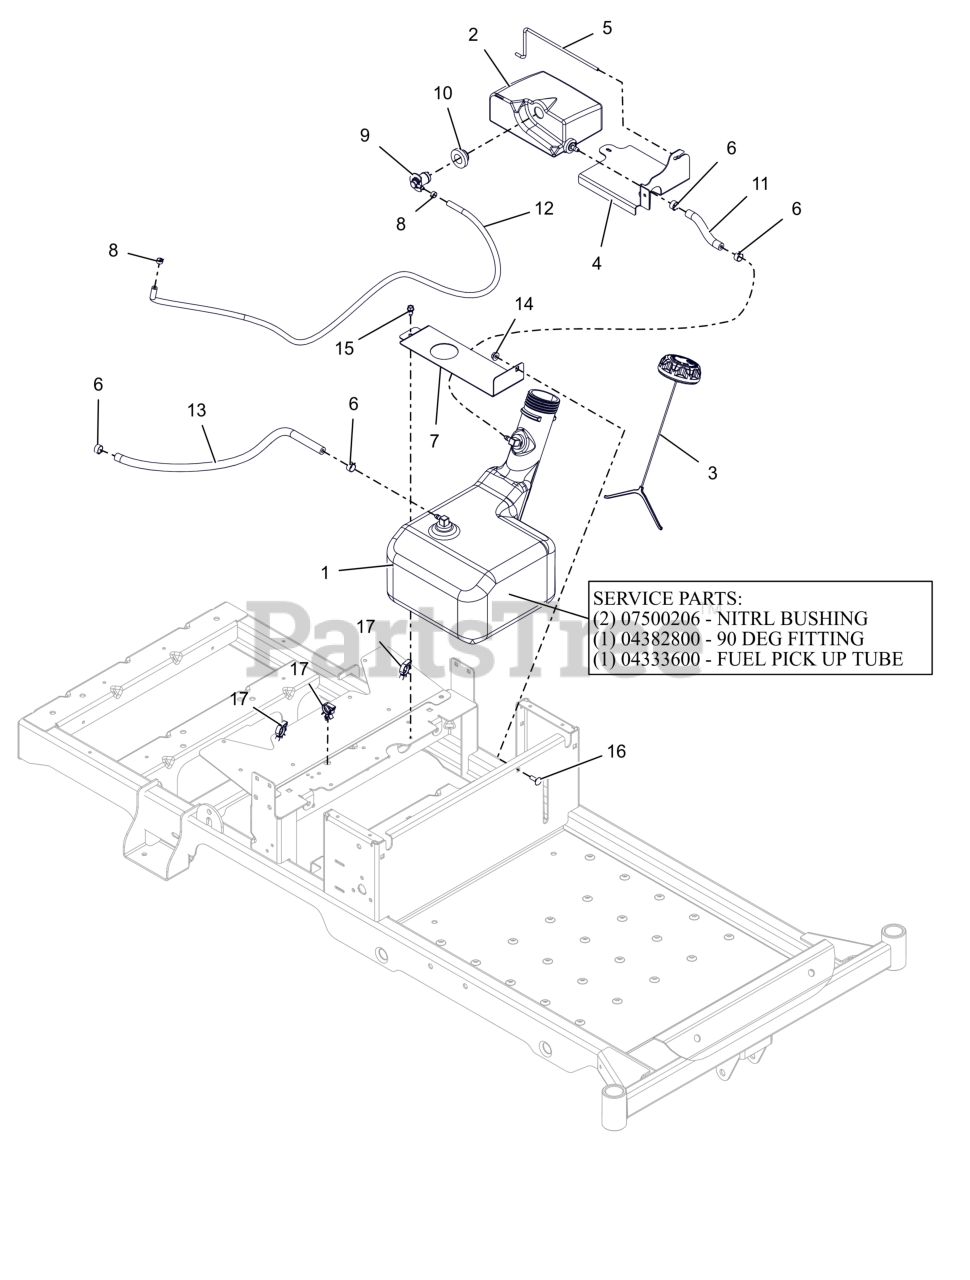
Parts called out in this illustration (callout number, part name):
1	ASM, FUEL TANK-ZOOM
1	BSHG-FLG .375X1.062X.625 NITR
1	FITTING, 90 DEG FUEL-PLASTIC
1	FUEL PICK UP TUBE
2	ASM, FUEL TANK - EXPANSION
3	CAP, FUEL VENT-IN 2.25" RATCH.
4	BRKT, EXPANSION TANK (ORANGE)
5	ROD, HOLDDOWN (BLACK)
6	CLAMP, FUEL LINE
7	BRKT, TANK STRAP
8	CLAMP-HOSE, SPRING .188
9	VALVE, 2-WAY
10	GROMMET, REMOTE VENT NITRILE
11	HOSE, .25 LOW-PERM BULK GAS
12	HOSE, .188 LOW-PERM BULK GAS
13	HOSE, .25 LOW-PERM BULK GAS
14	NUT-LK-CTR-FLG .25-20 ZC120
15	SCR-TAP .25-20X.50 HWH ZCC
16	BLT, RHSN .25-20X.750 G5 ZCC
17	WIRE CLIP
